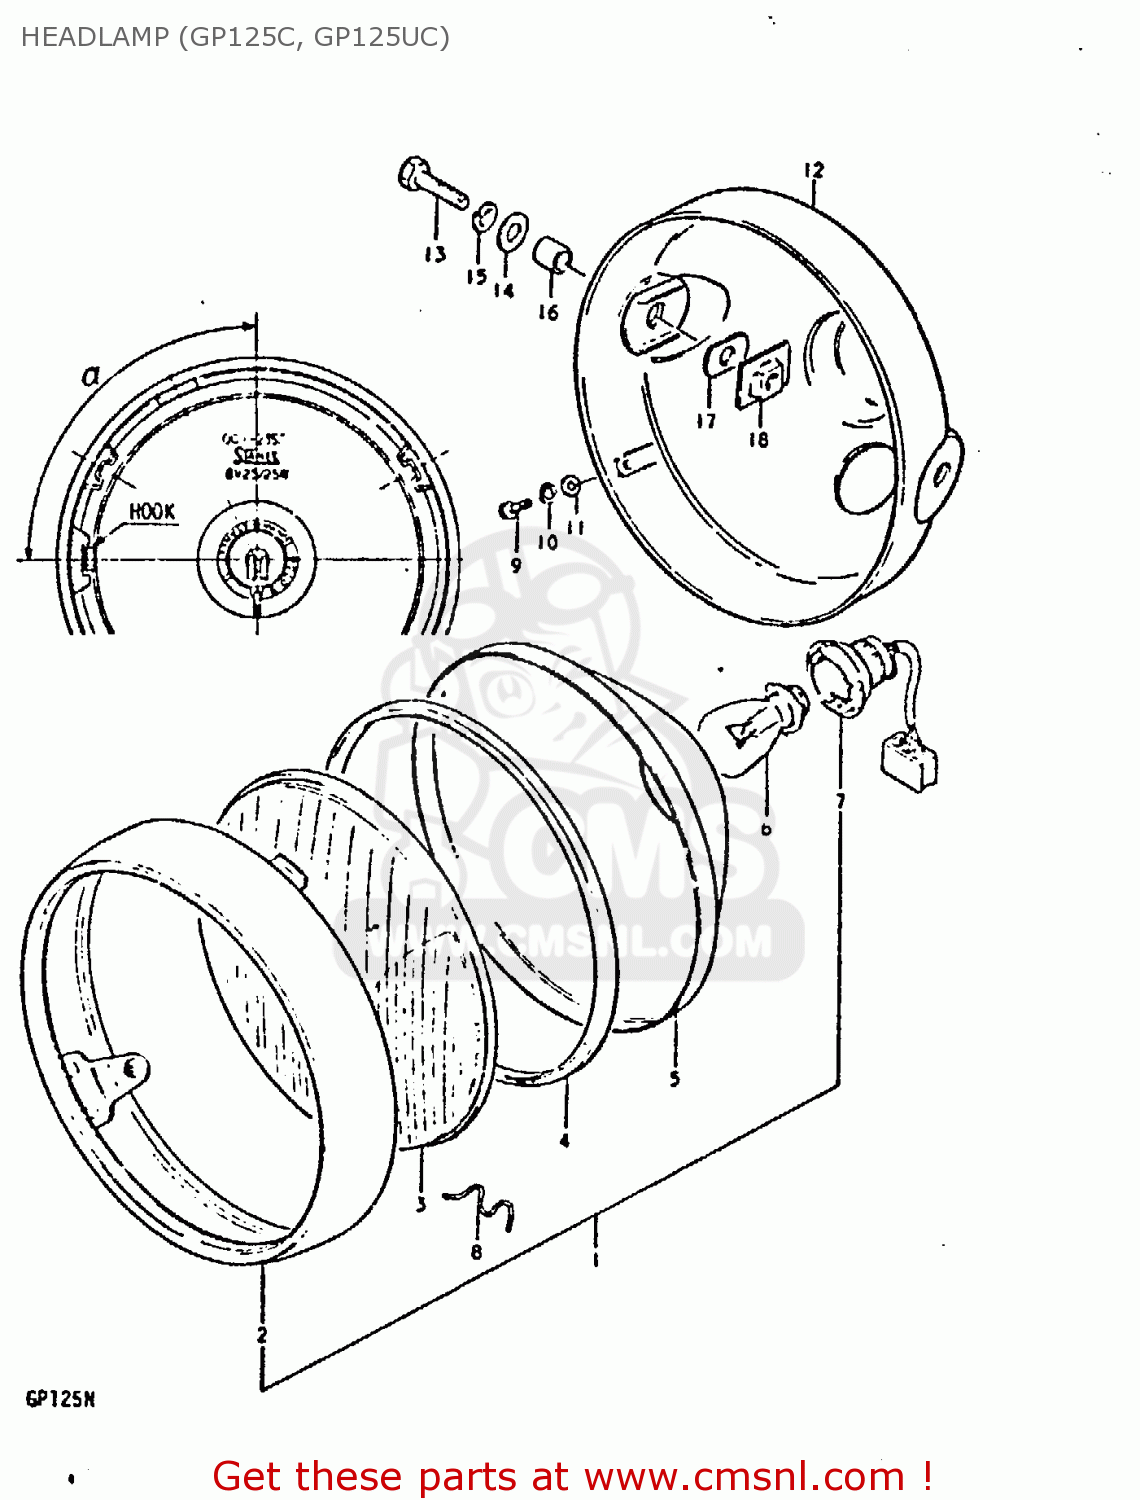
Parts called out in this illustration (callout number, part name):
9	SCREW
10	LOCK WASHER
11	WASHER
12	HOUSING,HEADLAMP
13	BOLT
14	WASHER
15	LOCK WASHER
16	SPACER (8.8X12X7)
17	CUSHION
18	PLATE,HEADLAMP HOUSING
